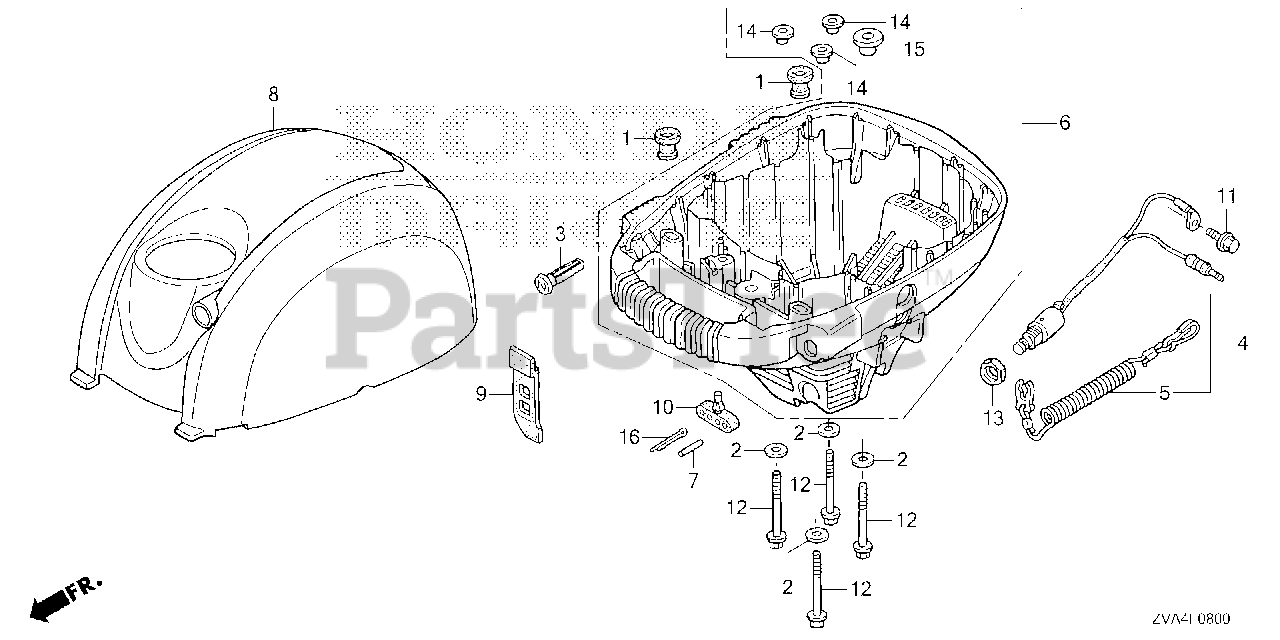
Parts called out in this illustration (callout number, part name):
1	RUBBER, TANK MOUNTING (C)
2	WASHER, PLAIN (6MM)
3	KNOB, CHOKE
4	SWITCH ASSY., EMERGENCY STOP
5	WIRE, EMERGENCY (SINGLE) (DUAL)
6	CASE, ENGINE (LOWER)
7	PIN, SHEAR
8	COVER, ENGINE *NHB14M* (AQUA MARINE SILVER METALLIC)
9	BELT, ENGINE COVER
10	HOLDER, PARTS
11	BOLT, FLANGE (5X10) (CT200)
12	BOLT, FLANGE (6X60)
13	NUT, HEX. (16MM)
14	COLLAR (6X4)
15	COLLAR, ENGINE CASE (LOWER)
16	PIN, SPLIT (3.0)
